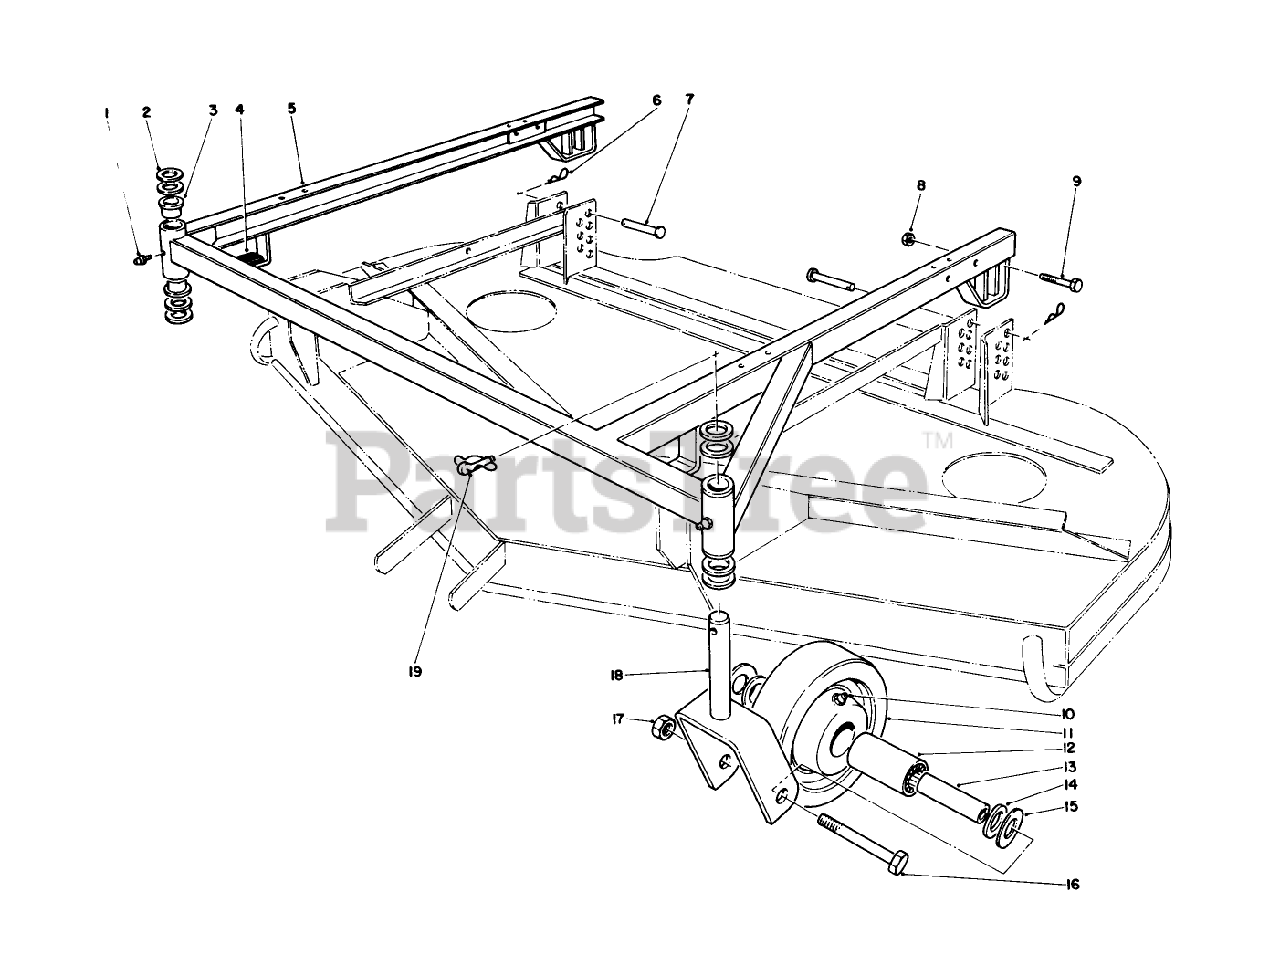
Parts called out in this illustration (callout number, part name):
1	FITTING-GREASE
2	WASHER-THRUST
6	PIN-HAIR
7	PIN-CLEVIS
8	NUT-LOCK, CONE
9	SCREW-HH
10	FITTING-GREASE
11	WHEEL
12	ROLLER BEARING
13	SPANNER BUSHING
14	BEARING RETAINER
15	THRUST WASHER
16	SCREW-HH
17	NUT-HEX
19	PIN-LYNCH
